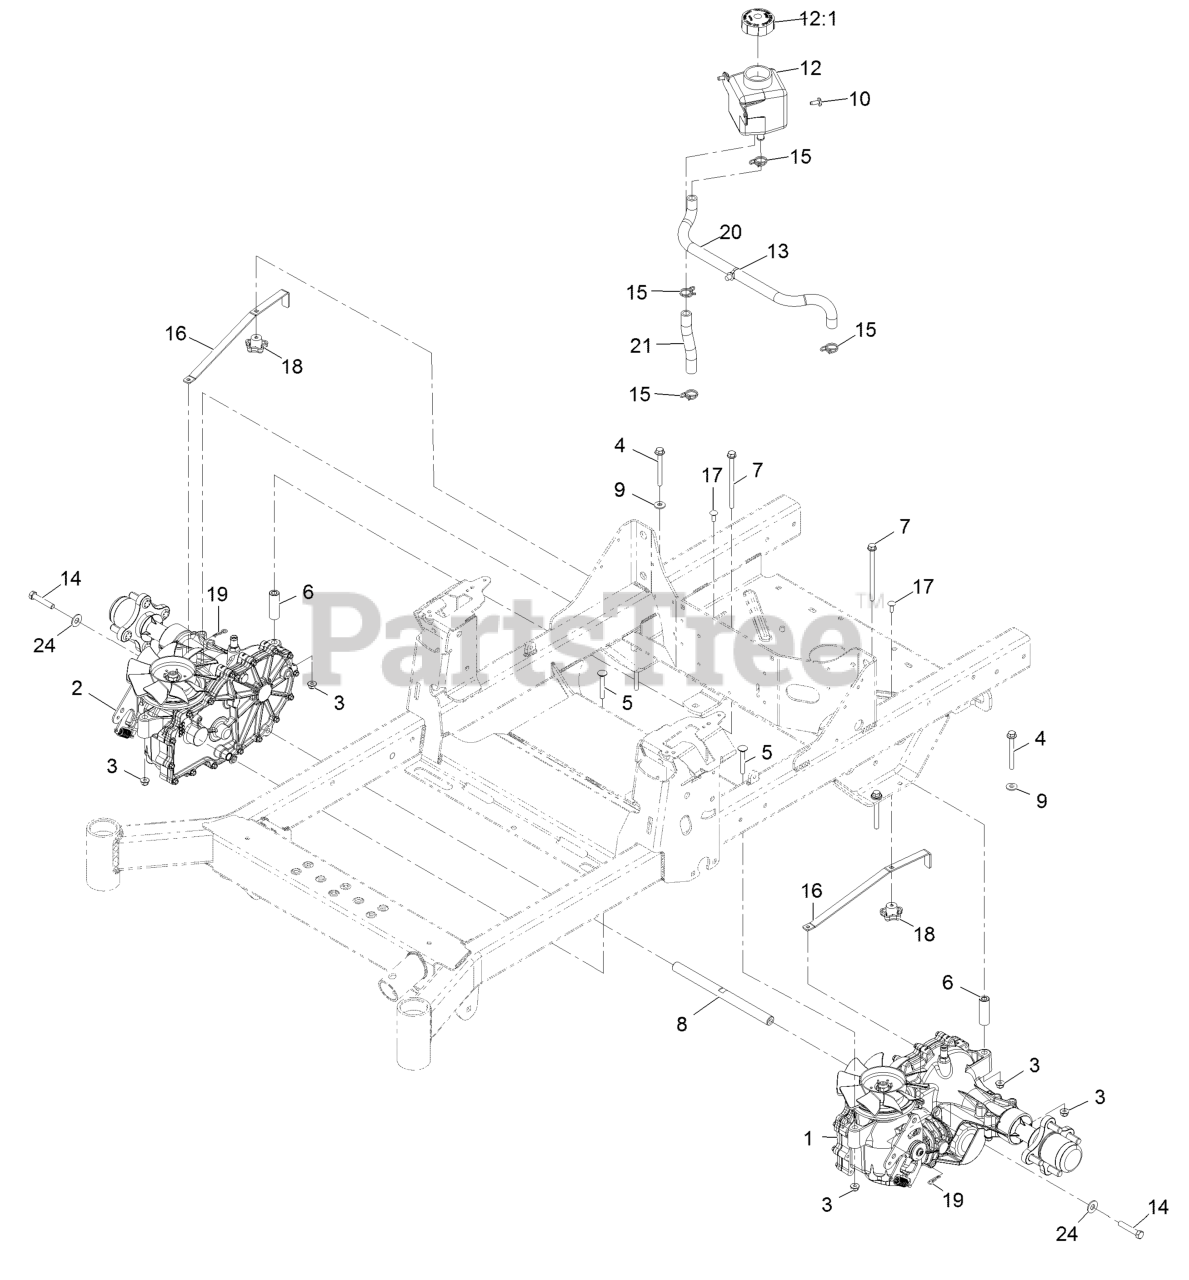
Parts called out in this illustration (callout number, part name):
1	Transaxle ASM
2	Transaxle ASM
3	Nut-Nyloc 5/16-18 Flg
4	Screw-HHF
5	Bolt-Carriage 5/16-18 X 2 1/4
6	Spacer-Hydro
7	Screw HHF
8	Shaft-Spacer
9	Washer-Spring Disc 5/16
10	Screw-1/4-20 X .65 Torx Plus
12	Vent-Tank, HYD
12:1	Cap-Reservoir, HYD
13	Clip-Tie
14	Screw-HH W/Loctite
15	Clamp-Hose
16	Arm-Bypass, Hydro
17	Bolt-Carriage 1/4-20 X 3/4
18	Knob-Handle
19	Hairpin-Cotter
20	Hose-Hydraulic
21	Hose-Hydraulic
24	Washer-3/8 Std
